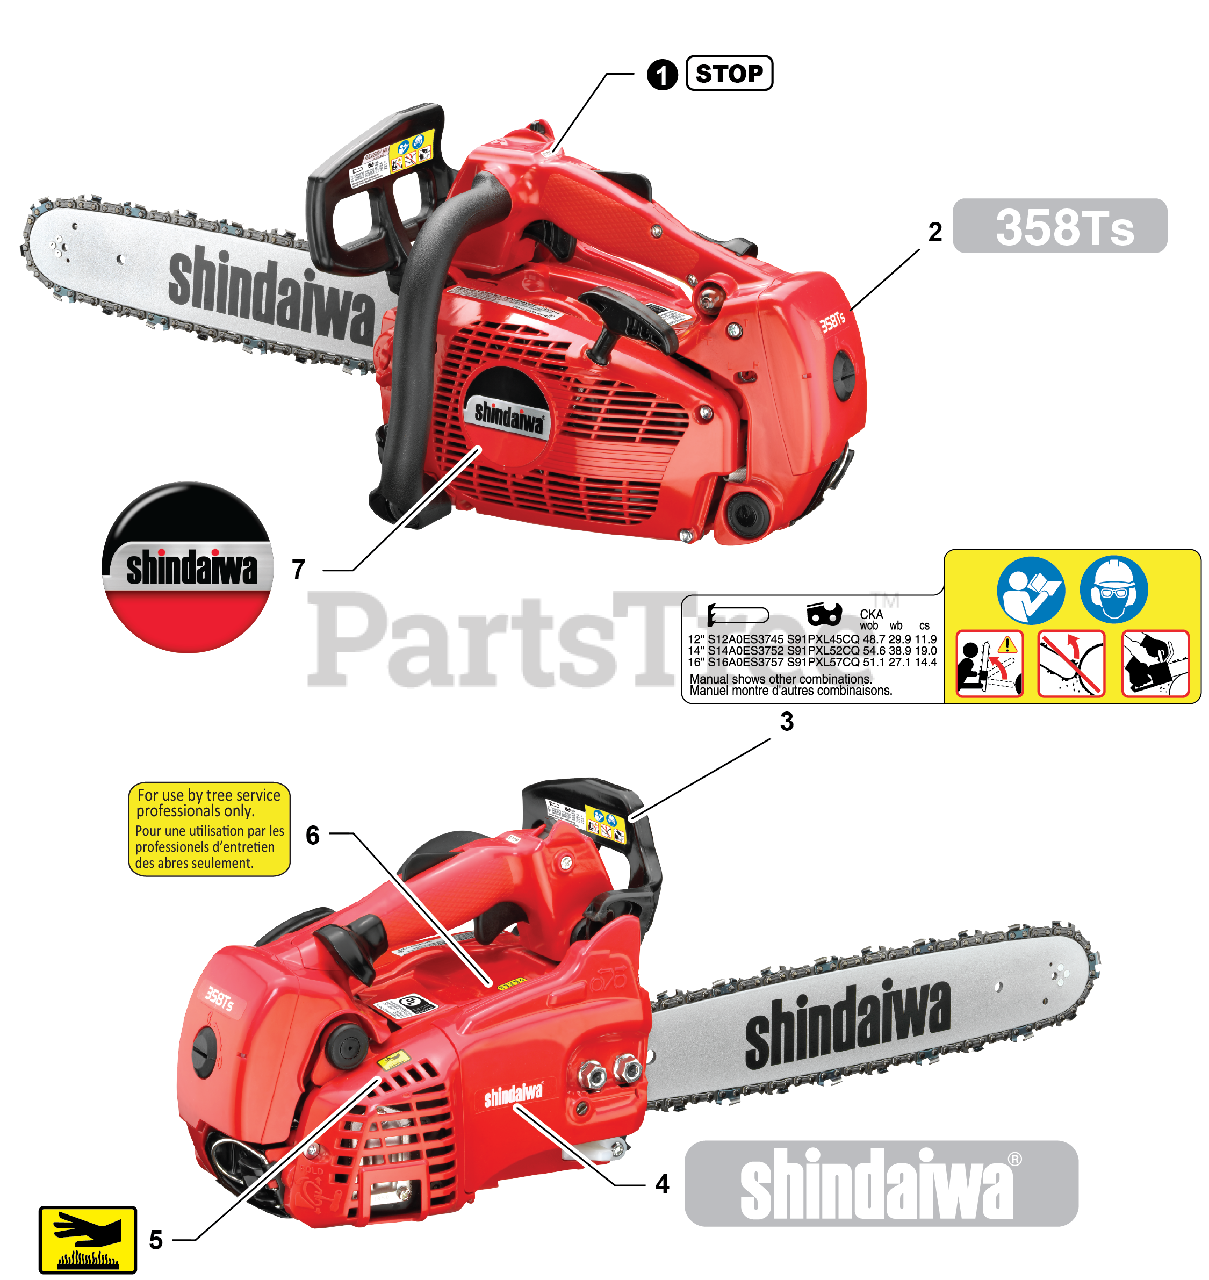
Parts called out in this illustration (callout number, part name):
1	LABEL - STOP
2	LABEL - MODEL
3	LABEL - CAUTION
4	LABEL - SHINDAIWA
5	LABEL - CAUTION - HOT
6	LABEL - CAUTION - PROFESSIONALS ONLY
7	LABEL - STARTER - SHINDAIWA
